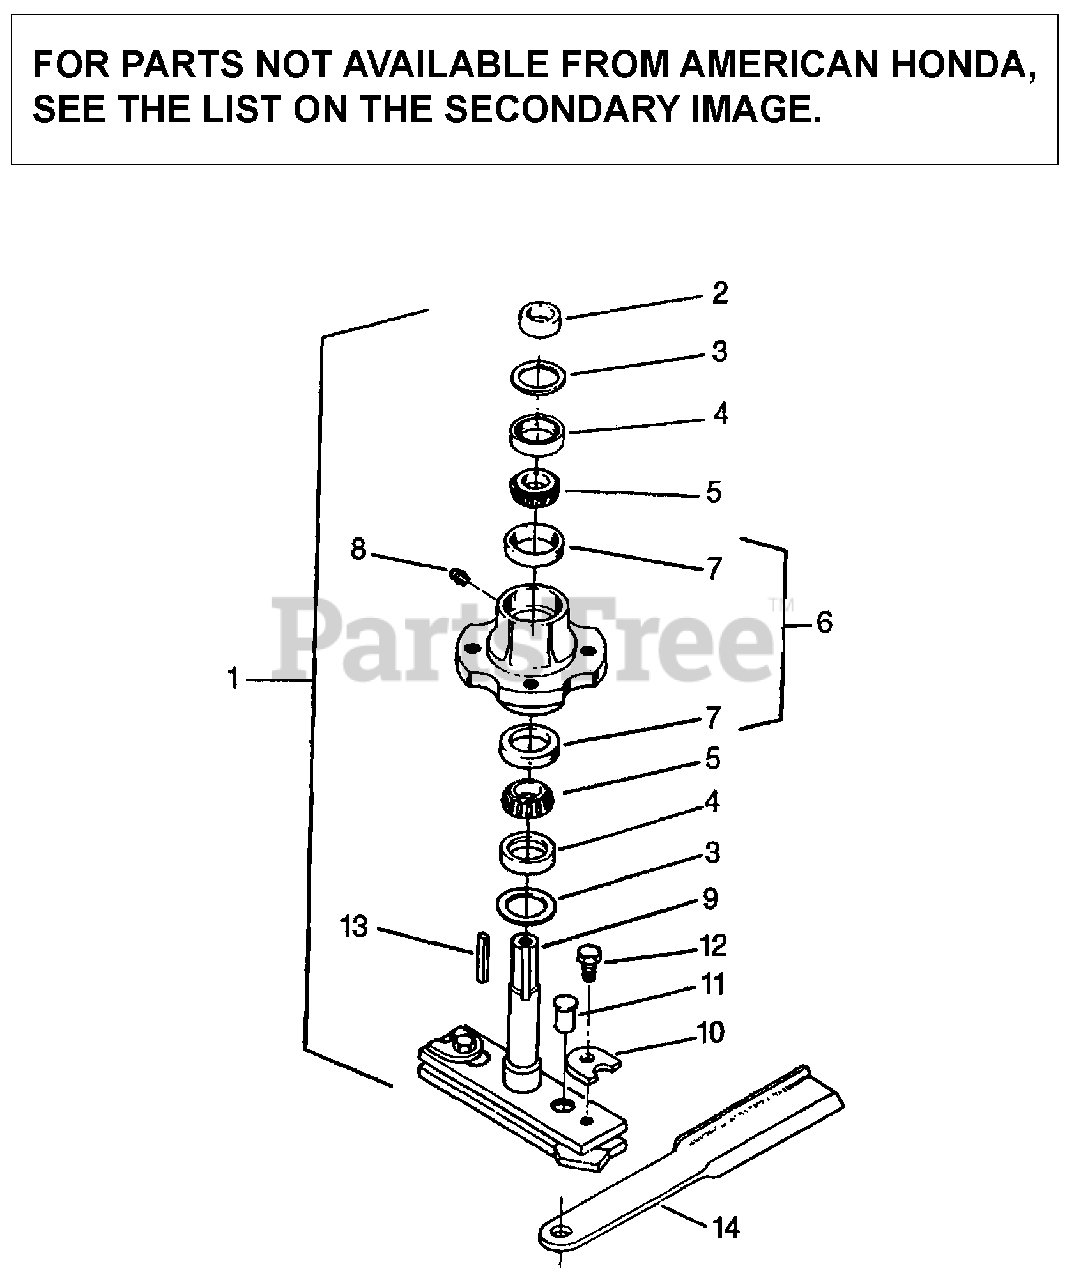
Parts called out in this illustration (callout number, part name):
1	SPINDLE, BLADE CW
2	SLEEVE (1-3/8X1-3/4 X5/8)
3	WASHER, FLAT
5	CONE, BEARING
6	HOUSING, SPINDLE
7	CUP, BEARING
9	SHAFT & CROSSBAR, SPINDLE
10	WASHER, BLADE PIN RETAINER
11	PIN, BLADE QD (NOT AVAILABLE)
12	SCREW, NYLON HEX. CAP
